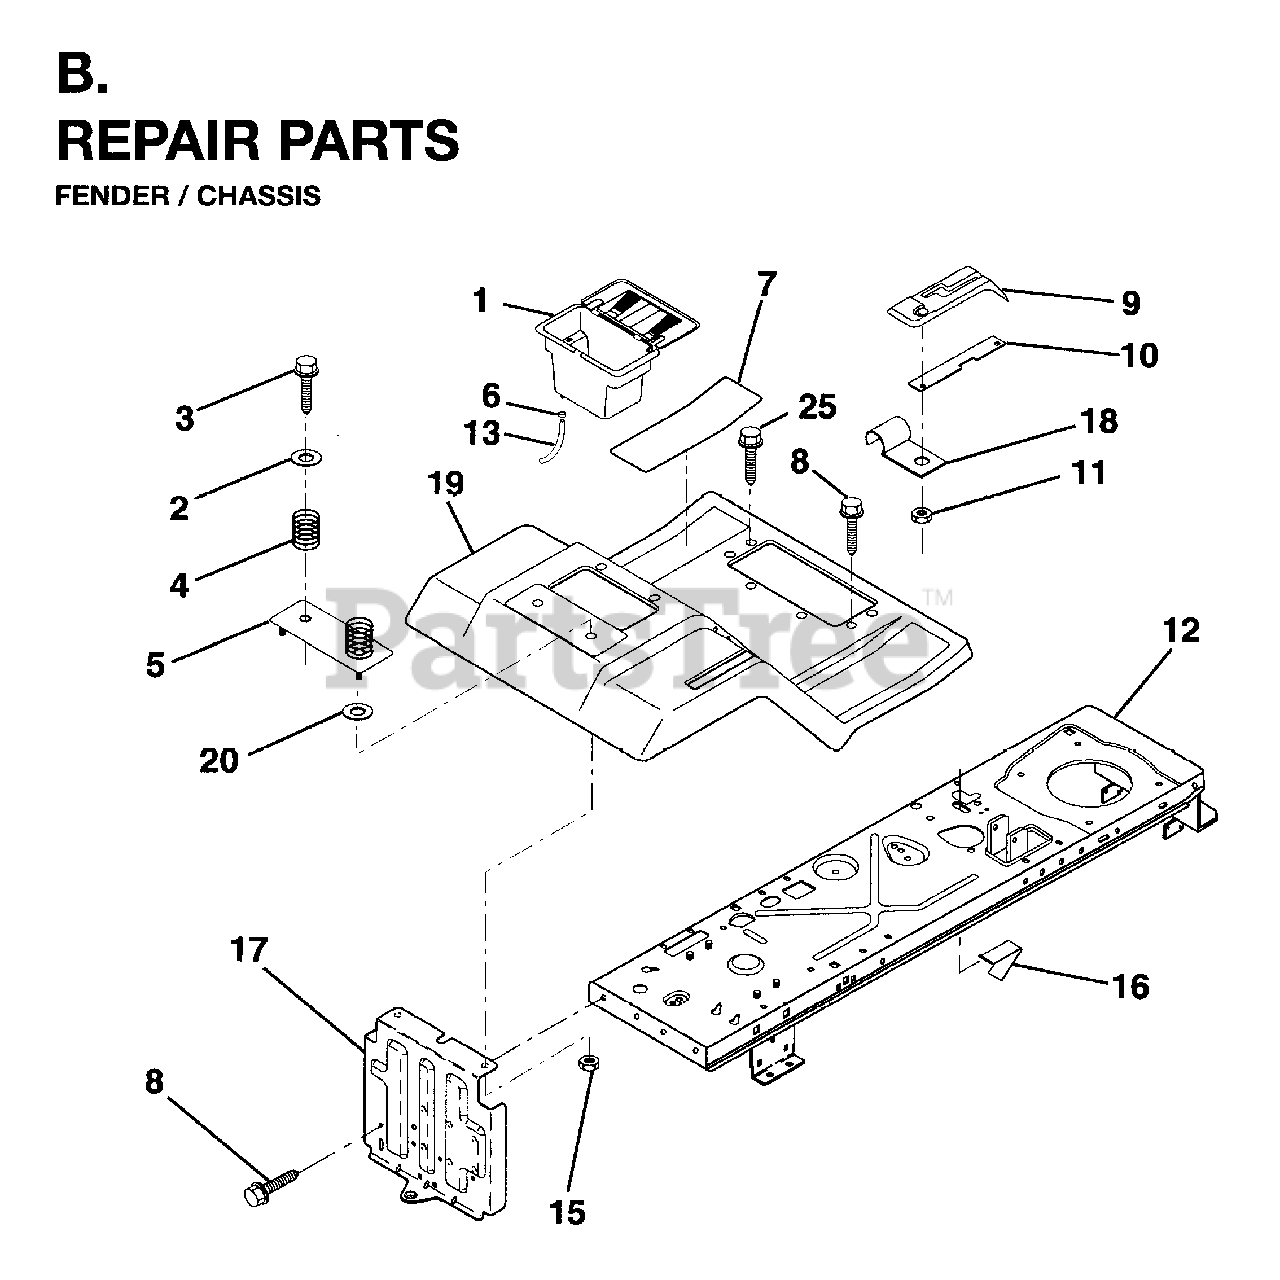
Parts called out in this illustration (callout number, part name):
1	BATTERY CASE
4	SPRING COMPRESSION
6	HOSE CLAMP T
7	PAD FOOTREST
8	BOLT
10	BAR, SHIFT LOCK
13	TUBE BATTERY DRAIN
15	NUT.CROWNLOCK.1/4
18	CLIP,INSULATOR
25	SCREW
